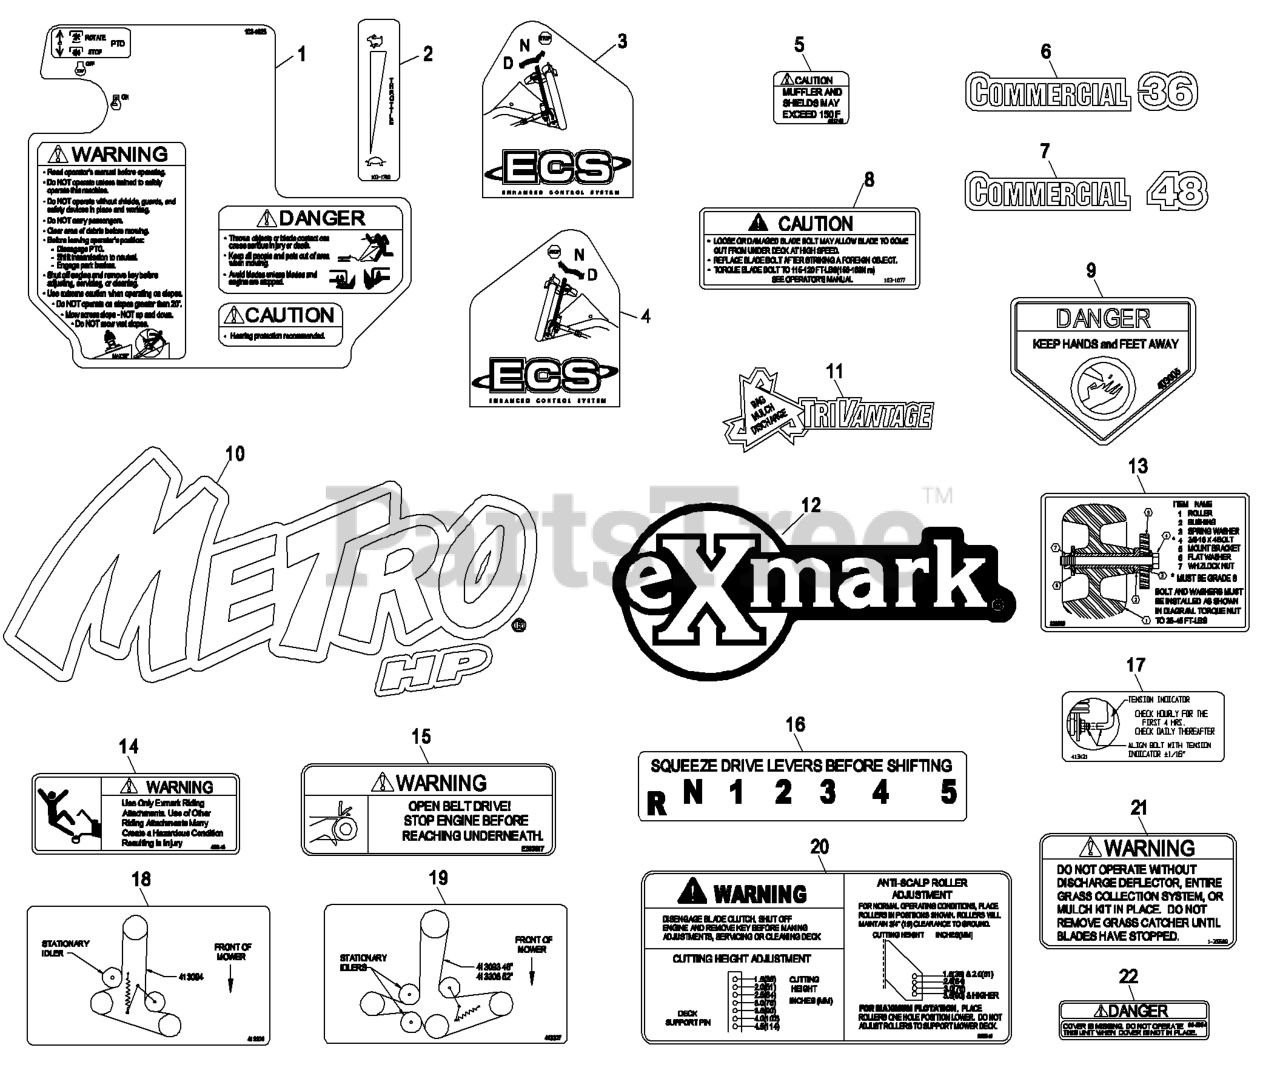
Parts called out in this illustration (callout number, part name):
1	DECAL,METRO ECS CONSOLE
2	DECAL,THROTTLE ONLY
3	DECAL,LH ECS INSTRUCTION
4	DECAL,RH ECS INSTRUCTION
6	DECAL,COMMERCIAL 36
7	DECAL,COMMERCIAL 48
8	DECAL,BOLT TORQUE
9	DECAL-DANGER
12	DECAL,EXMARK LOGO
13	DECAL,ROLLER MOUNTING
14	DECAL,SULKY WARNING
15	DECAL,BELT DRIVE
16	DECAL,SHIFTER
17	DECAL,INDICATOR
18	DECAL,BELT ROUTING
19	DECAL,BELT ROUTING
20	DECAL,ANTI SCALP
21	DECAL-WARNING, DISCHARGE
22	DECAL-COVER, MISSING
